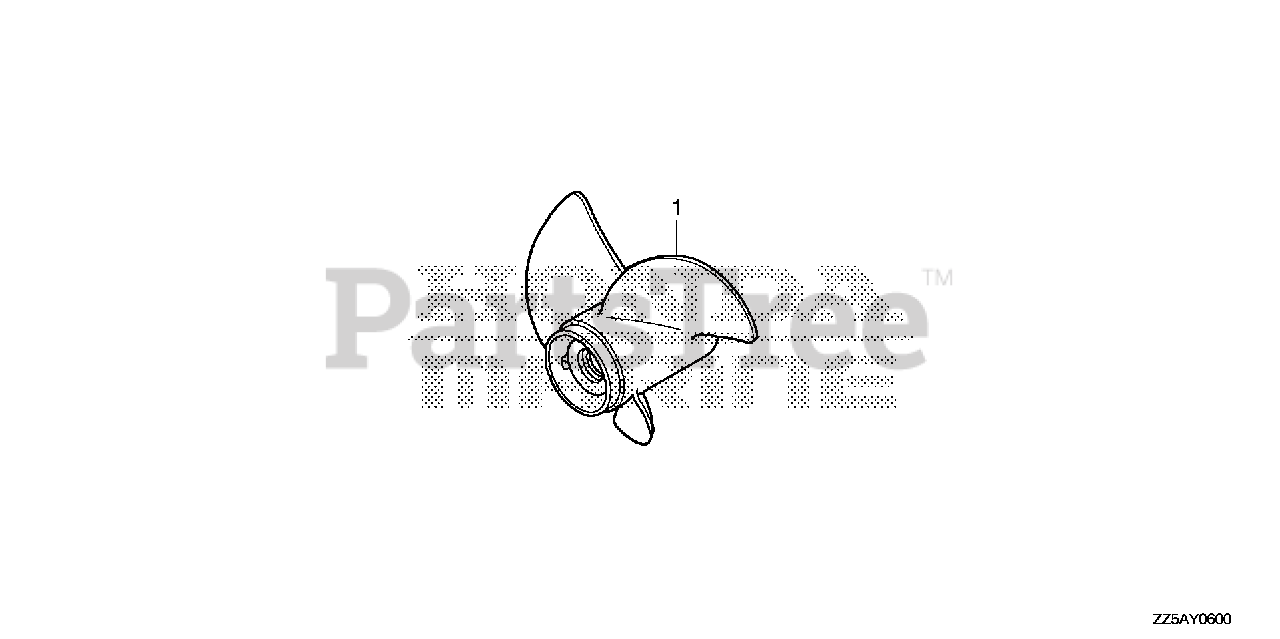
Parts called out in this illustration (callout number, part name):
1	PROPELLER, THREE-BLADE (11-3/8X12) *NH283* (STIN GRAY)
1	PROPELLER, THREE-BLADE (12-1/8X9) *NH283* (STIN GRAY)
1	PROPELLER, THREE-BLADE (11-5/8X11) *NH283* (STIN GRAY)
1	PROPELLER, THREE-BLADE (11-1/8X13) *NH283* (STIN GRAY)
1	PROPELLER, THREE-BLADE (11-1/8X14) *NH283* (STIN GRAY)
1	PROPELLER, THREE-BLADE (11X15) *NH283* (STIN GRAY)
1	PROPELLER, THREE-BLADE (11-1/4X13) *NH283* (STIN GRAY)
1	PROPELLER, THREE-BLADE (11-1/2X12) *NH283* (STIN GRAY)
1	PROPELLER, THREE-BLADE (11-3/4X10) *NH283* (STIN GRAY)
1	PROPELLER, THREE-BLADE (11-1/2X14-1/4) *NH283* (STIN GRAY)
